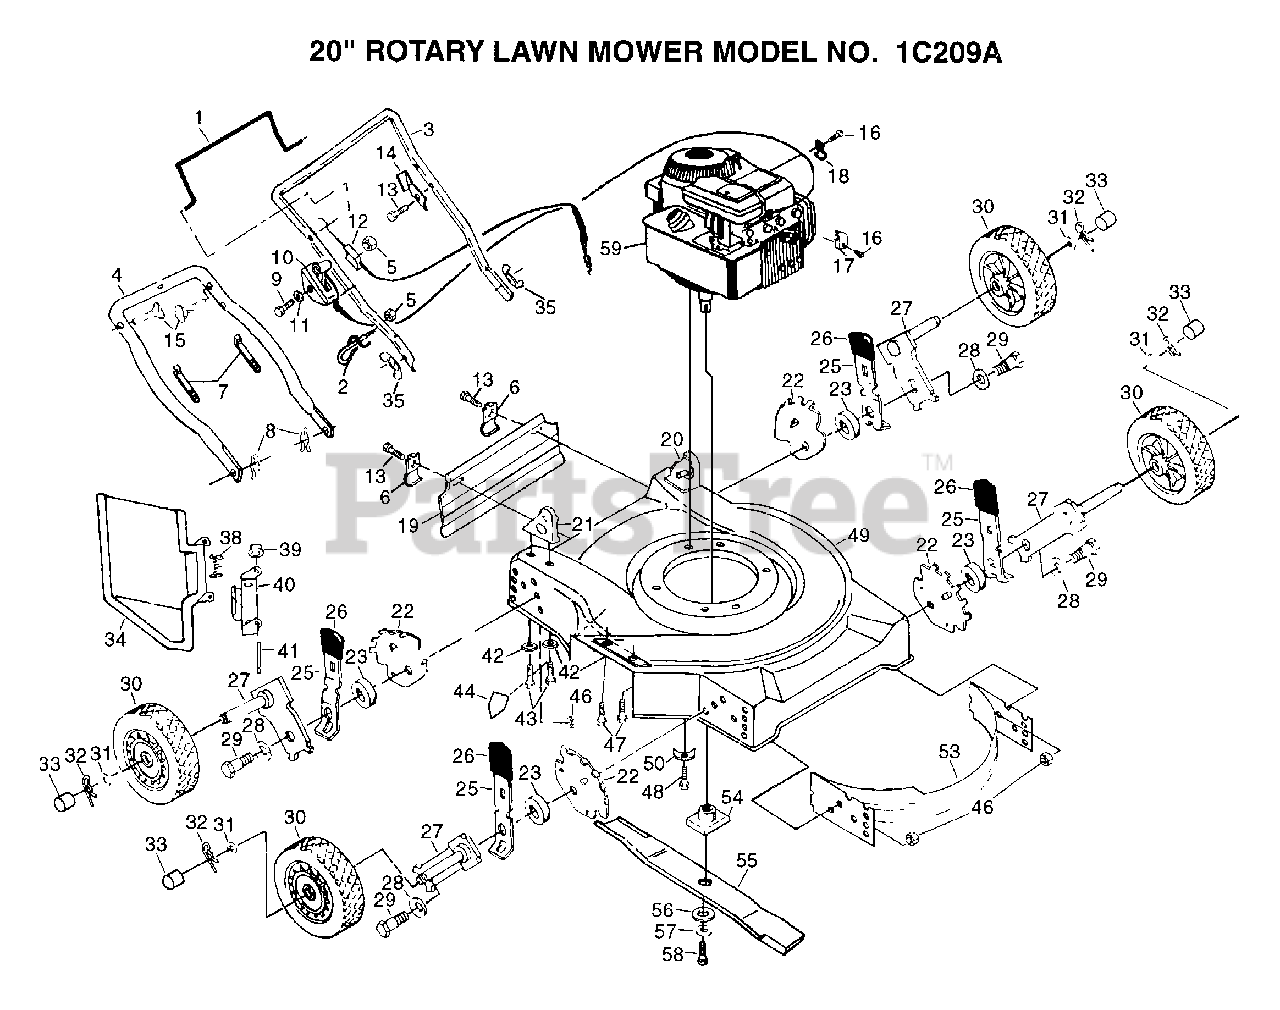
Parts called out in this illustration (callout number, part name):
1	CONTROL BAR PM
2	ROPE GUIDE
6	"BRKT,DEFL PM"
8	HAIRPIN COTTER
10	CONTROL THROTTLE
11	WASHER PM
12	"CABLE,ENG ZONE CO"
13	TAPPING SCREW
14	"BRKT,UPSTOP"
15	BOLT.HANDLE.LM
16	SCREW PM
17	CABLE CLAMP
18	"CLIP,CABLE"
25	SPRING SELECTOR
26	KNOB PM
27	AXLE ARM
28	"WASHER, BELLEVIL."
30	WHEEL&TIRE
31	WASHER
32	RETAINER CLIP PM
33	HUB CAP-PLASTIC
34	"GRD,DISCHARGE"
35	"NUT,WING PM"
38	"SPRING,TORSION"
39	PUSH ON SPEED NUT
40	"BRKT,HSG "
42	STEEL WASHER
43	SCREW
44	DECAL HYT
46	LOCKNUT PM
47	SCREW
48	SCREW
49	"KIT.HSG.20""SDPUSH"
54	BLADE ADAPTOR
55	BLADE.STAND.20INC
56	"WASHER,HARDEN"
57	LOCKWASHER
58	SCREW
